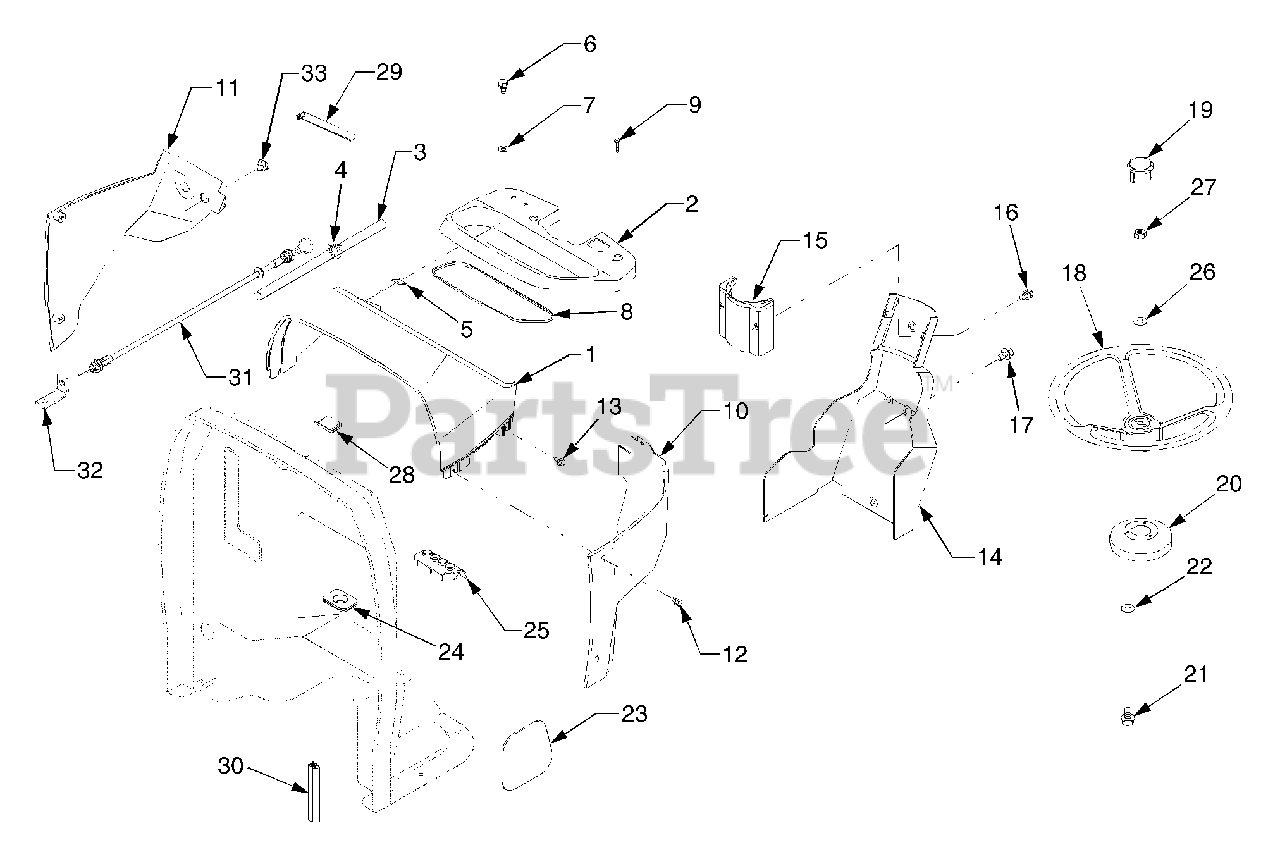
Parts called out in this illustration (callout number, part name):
1	Hood, Instrument
2	Cover, Instrument
7	Washer, Plain
10	Cover, Instrument (LH)
11	Cover, Instrument (RH)
14	Cover 1, Steering
15	Cover 2, Steering
18	Steering Wheel
19	Cap, Steering Wheel
20	Cover, Steering Wheel
22	Washer, Plain
26	Washer, Spring
31	Wire, Engine Stop
